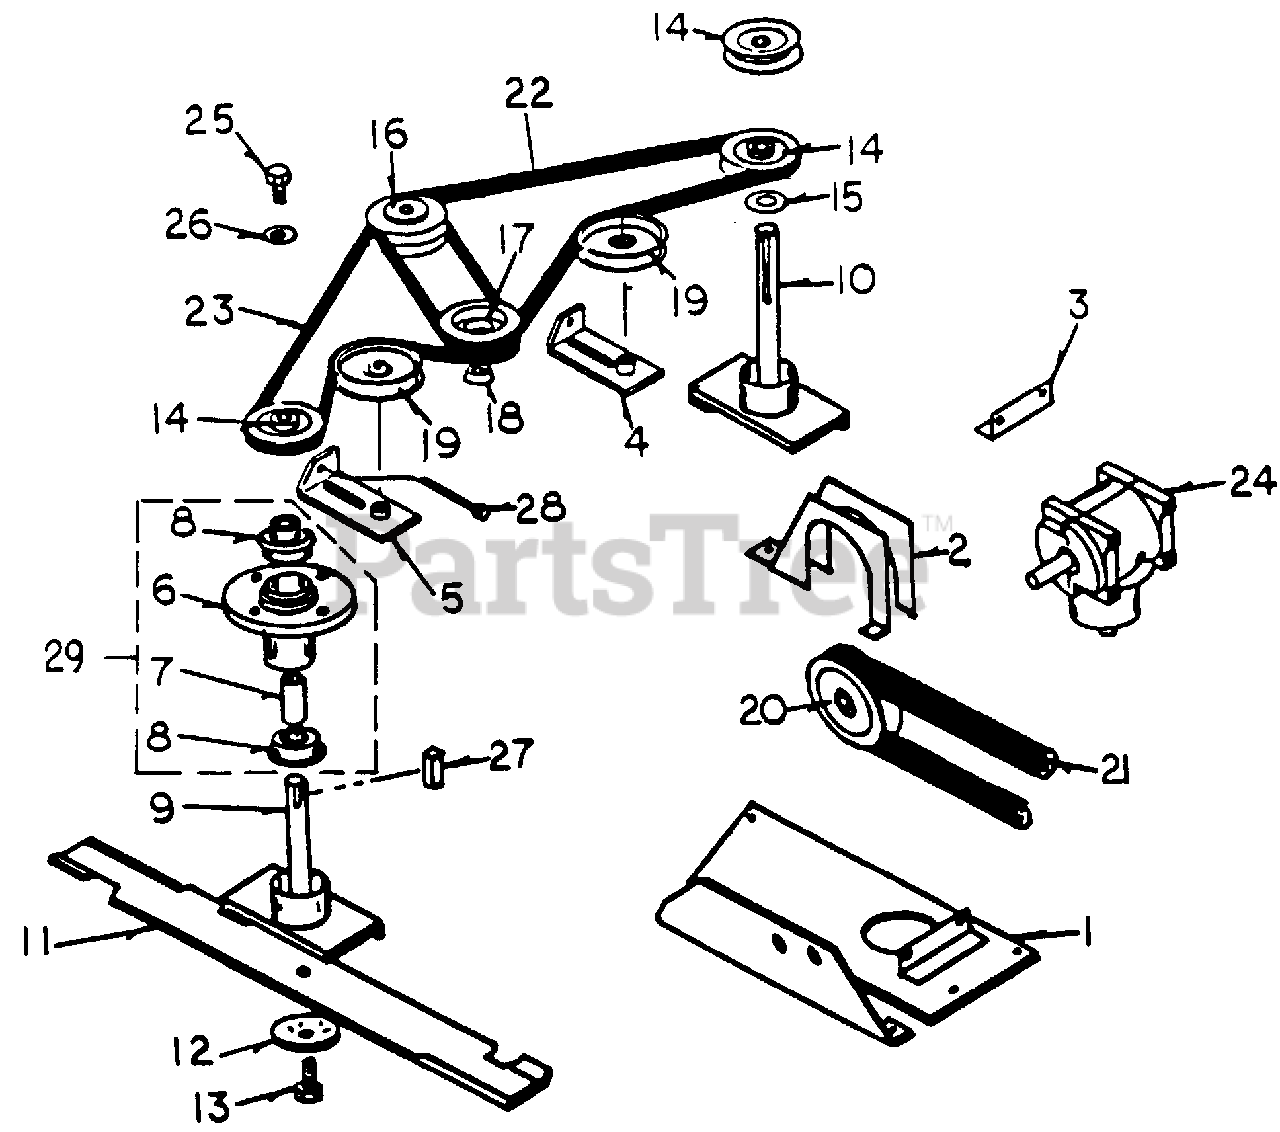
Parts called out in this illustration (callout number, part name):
2	Belt Guard
3	Gearbox Mount Angle
4	Belt Tightener
5	Belt Tightener
6	Spindle Housing
7	Spindle Spacer
8	Spindle Bearing
9	Spindle Shaft
11	Blade
13	Hex Bolt, 3/8-24 x 1 1/4"
14	Spindle Pulley
16	Spindle Pulley, Double A
17	Gearbox Pulley, Output
18	Hub
20	Gearbox Pulley, Input
21	Deck Drive Belt
22	Deck Belt
25	Hex Ny-Lock Bolt, 5/16-14 x 3/4"
26	Washer, 5/16", 10 GA
27	Key Stock, 3/16"
28	Adjustment Bolt
29	Spindle Housing Assembly
